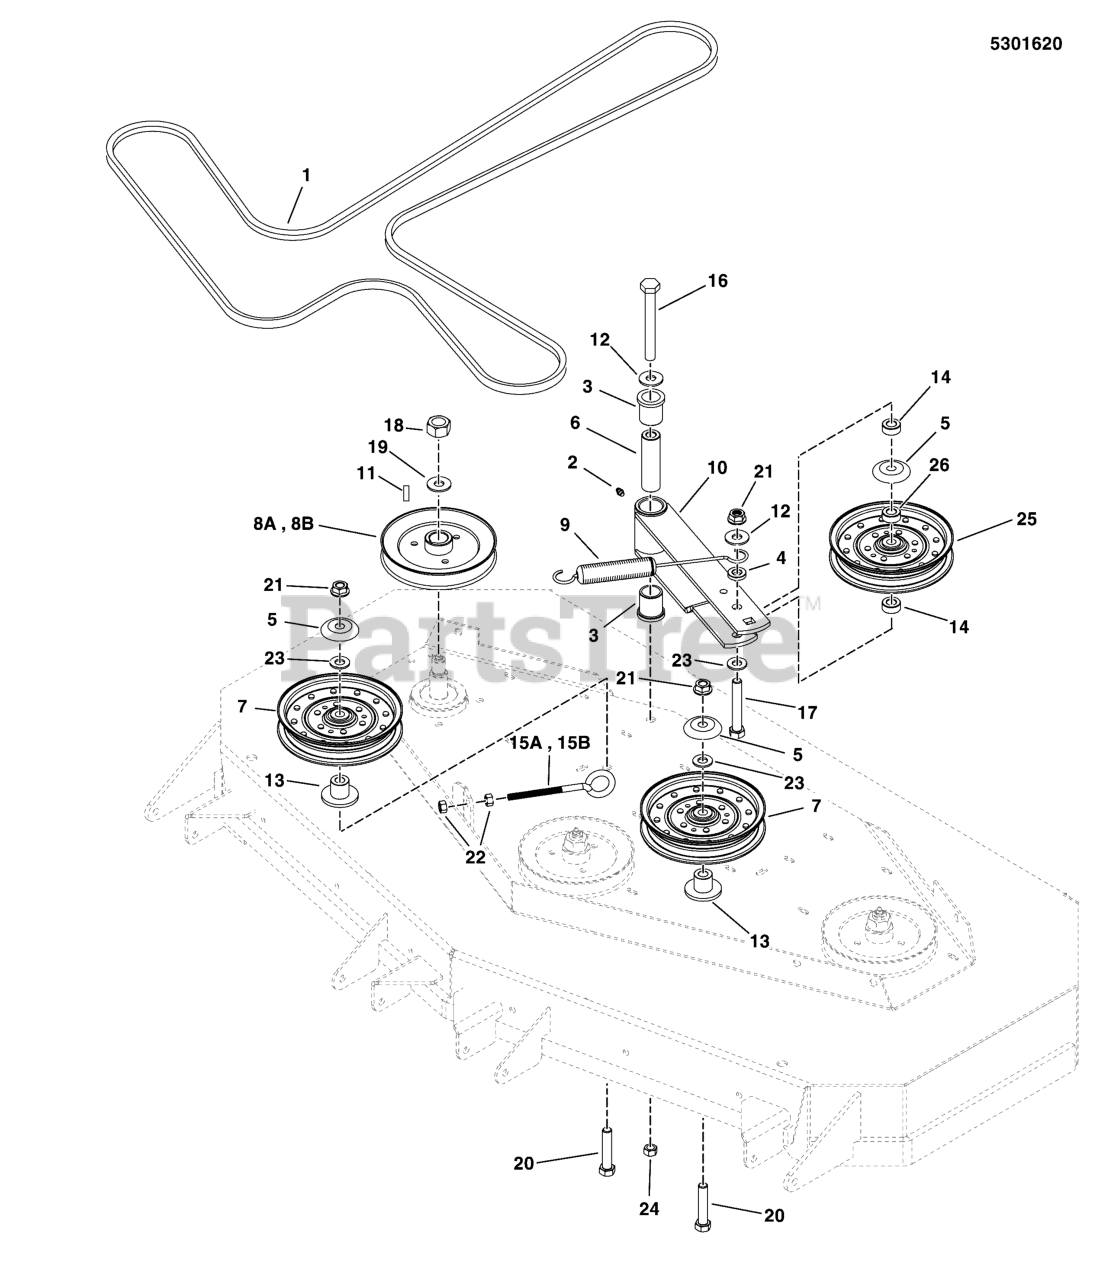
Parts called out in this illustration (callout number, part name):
1	BELT, 5V, 182.00"EL, LRG ARAMID, WRP, RC
2	GREASE FITTING, 45 DEGREE
3	BUSHING, FLANGE
4	SPACER, .52 X 1.00 X .22, PM, CZ
5	SHIELD, PULLEY BEARING
6	SPACER, .52 X 1.00 X 3.50
9	SPRING-EXTENSION, SWIVEL END
10	WELD, IDLER ARM - BLK
11	KEY, 1/4 SQ X 1-1/4
12	WASHER, 1/2 USS
13	IDLER MOUNT
14	SPACER, .52 X 1.00 X .44
16	BOLT-1/2-13 X 5 GD5 YZ
17	BOLT, 1/2-13 X 3-1/4, HEX HD, GD5, CZ (SV)
18	NUT, 3/4-16 HEX
19	WASHER, 3/4 BELLEVILLE
20	BOLT, 1/2-13 X 2-1/2" GD5 CZ
21	NUT, Hex Flange, Nylock, 1/2-13
22	NUT, 3/8-16 HEX, YZ
23	WASHER, 1/2 SAE
24	NUT, 1/2-13 HEX NYLON LOCK
25	PULLEY, IDLER - 5
26	INSERT, BEARING
